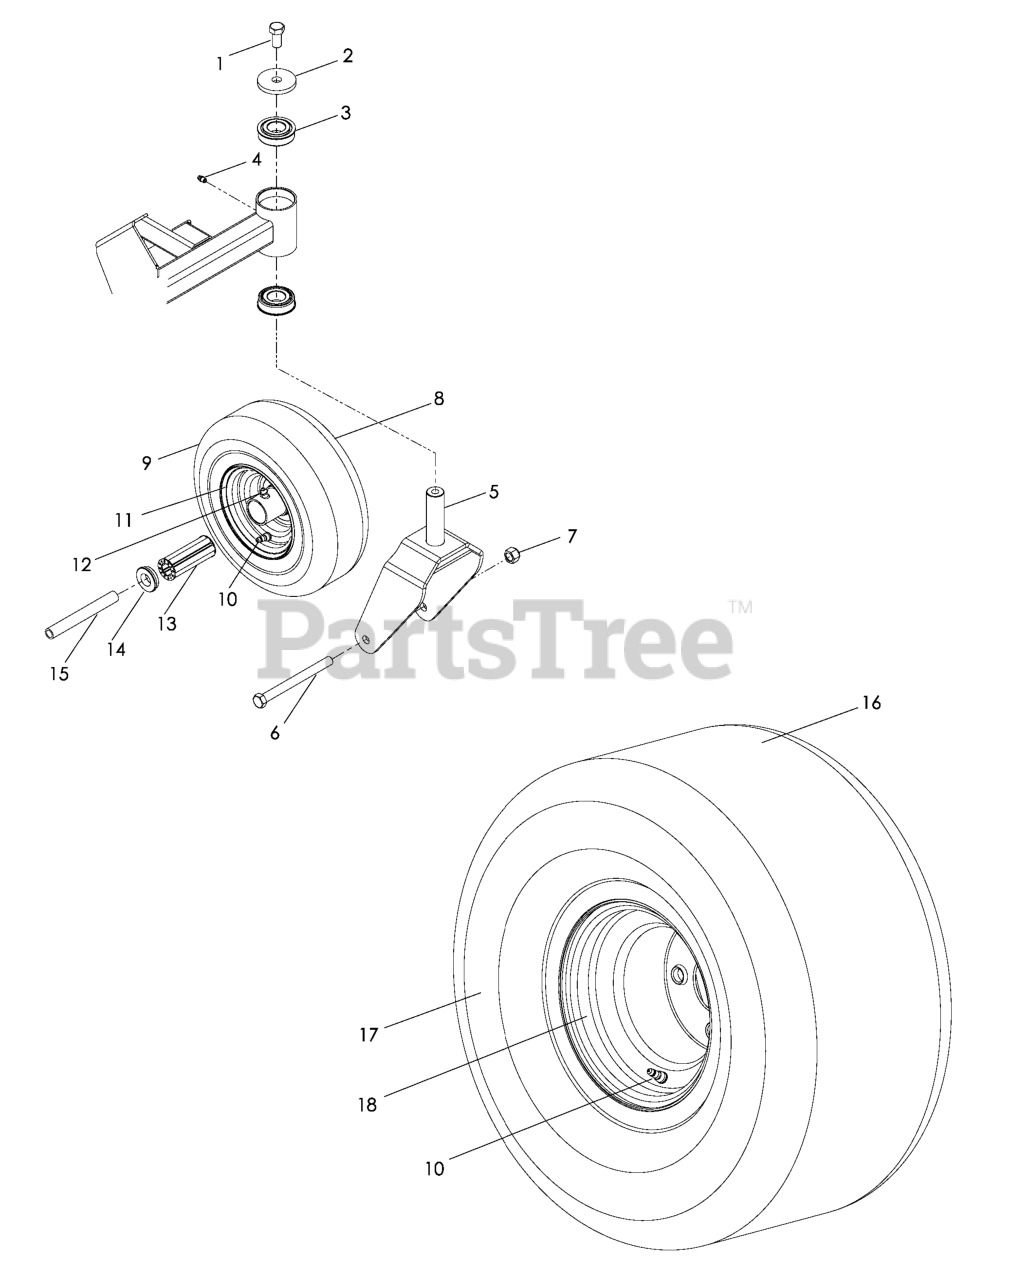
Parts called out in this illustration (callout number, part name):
1	HHCS 1/2-13 X 1
2	HEAVY WASHER
3	BEARING FLANGED
4	ZERK
5	CASTER YOKE - PAINTED
6	HCS 1/2C X 5 1/2
7	NUT 1/2-13 HEX NYLOC ZD
8	TIRE/WHEEL.CASTER
9	TIRE - CASTER
10	VALVE STEM TR-412
12	ZERK
13	ROLLER BEARING-CAGED 3 1/4'
14	BEARING RETAINER
17	TIRE ASM 18 X 8.5-8
18	RIM.8X7.W/8".OFFSET.SILVER.ZTR
